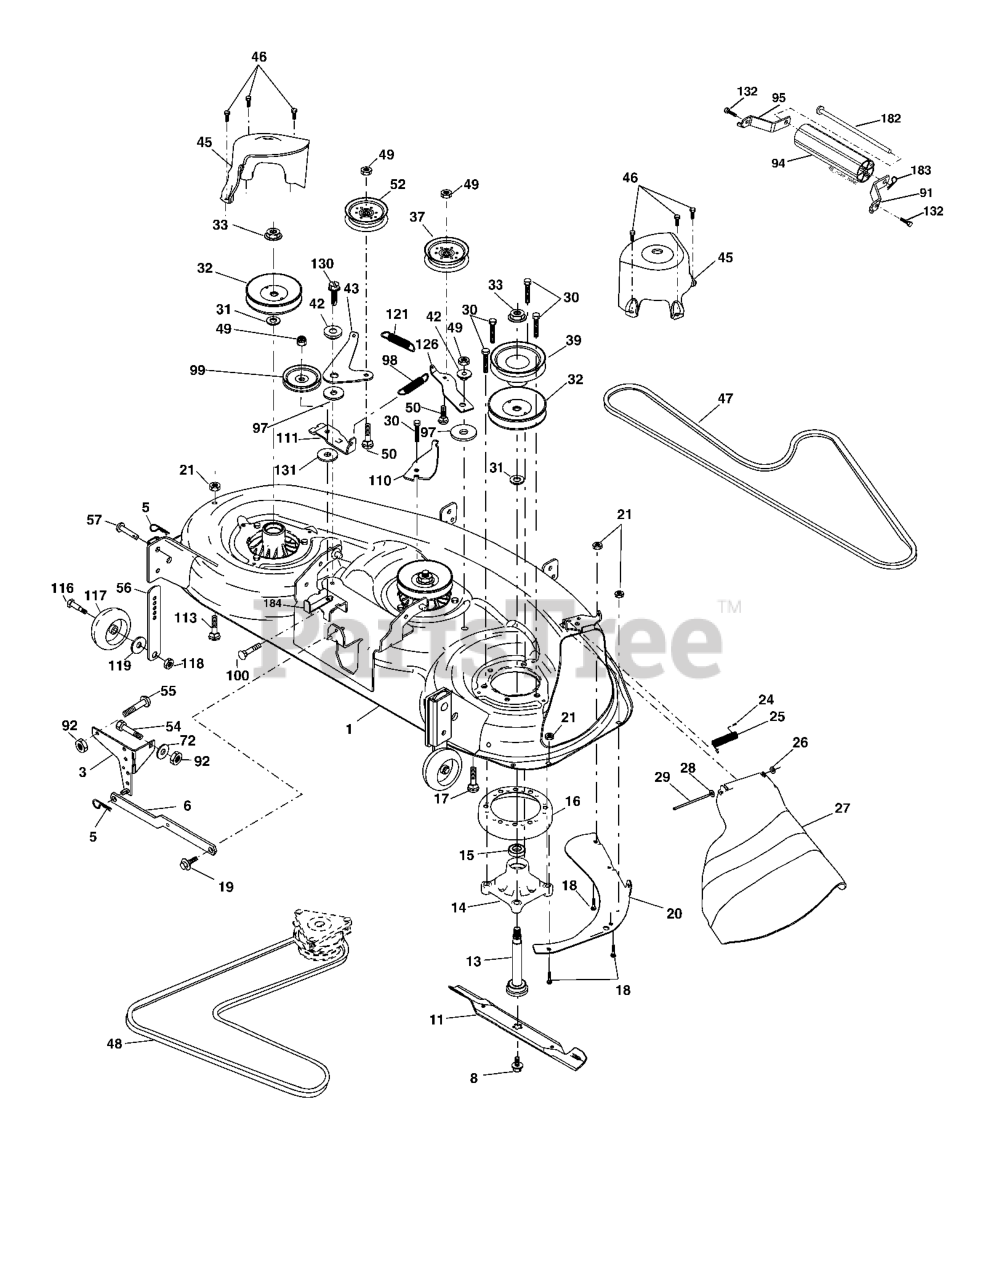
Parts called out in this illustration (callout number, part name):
1	DECK.SVC.4.GA.WHLS.48".GREY
3	BRKT ASM SWAY BAR
5	RETAINER-SPRNG RB
6	BAR SWAY DECK
8	BOLT 7/16 ASM BLADE
11	48" HI-LIFT BLADE
13	SHAFT, ASM. MANDEREL SEALED
14	HOUSING, MANDREL 48"
15	BEARING
16	STRIPPER.MANDREL.ROUND.BLACK
17	BOLT
18	BOLT
19	BOLT SHD 5/16-18
20	BAFFLE, VORTEX MWR
21	LOCKNUT
24	CAP-SLEEVE LT
25	SPRING, TORSION
26	NUT PUSH M
27	DEFLECTOR SUBS TO 532 180655
28	Washer 11/32 x 5/8 x 16 Ga SD
29	ROD.HINGE
30	SCREW, WASHER HEAD
31	WASHER.SPACER.MANDREL
32	PULLEY, MANDREL
33	NUT, FLG TOPLOCK 9/16"
36	WASHER
37	PULLEY.IDLER.FLAT
39	PULLEY.DRIVEN.DECK.48'
42	SPACER.RETAINER.MOWER
43	ARM, IDLER SECONDARY
45	COVER.MANDREL.DECK.48"
46	SCREW.1/4-20X5/8
47	V-BELT, 48"SECONDARY
48	V-BELT PRIMARY 48"
49	LOCKNUT
50	BOLT.3/8-16X1.50
52	PULLEY.IDLER.FLAT.46.PR.DR.
54	BOLT
55	BOLT D
56	BAR.ADJUST.WHEEL.ANTI.SCALP.BL
57	RIVET.PIN.HEAD.YELLOW.
72	WASHER
91	BRKT.NOSEROLLER.RH.48"
92	NUT
94	NOSE ROLLER 48"
95	BRKT.NOSEROLLER.LH.48"
97	WASHER
98	SPRING PRIMARY DRIVE
99	IDLER PULLEY
100	BOLT
110	ARM, SPRING SECONDARY
111	ARM SPRING FIXED TENSION
116	SHOULDER BOLT
117	WHEEL GAGE DONUT
118	LOCKNUT
119	WASHER.5/16.FLAT.STE.STD.
121	SPRING.DRIVE.SECONDARY.48".DEC
126	ARM, IDLER PRIMARY DECK
130	SCREW 3/8-16X1
131	Washer 13/32 x 1.00 x 6 Ga.
132	SCREW, 3/8-16X3/4
133	BOLT.CARR.SQNK.5/16-18UNC.X3/4
182	ROD.ROLLER.NOSE.NARROW.48"
183	SPRING RETAINER
184	KEEPER BELT IDLER PLATED
